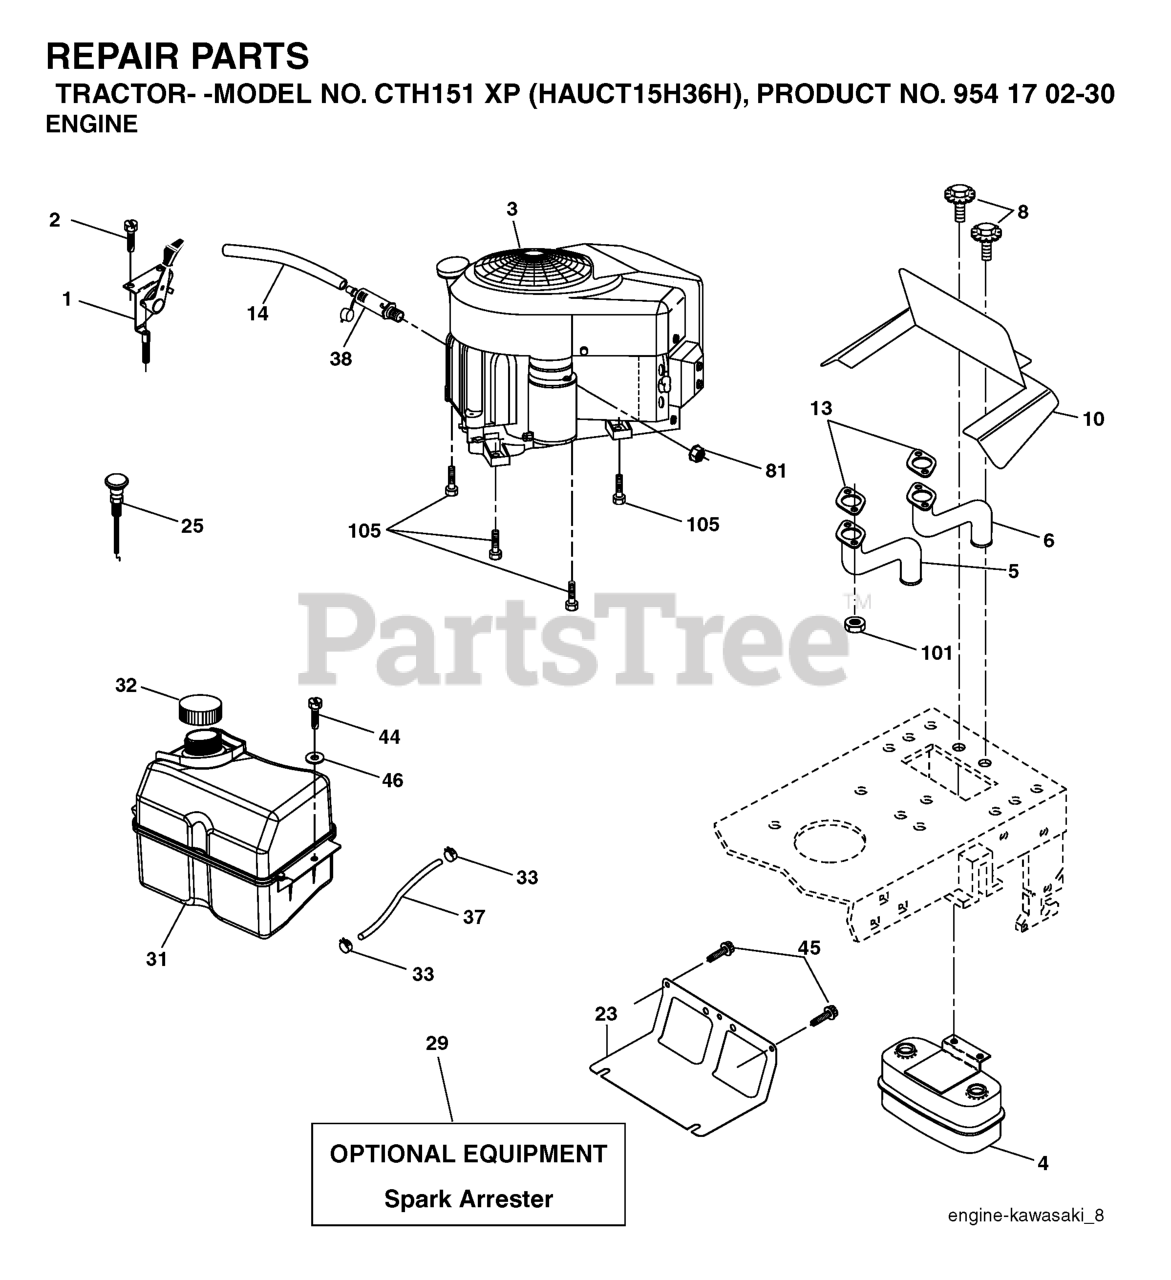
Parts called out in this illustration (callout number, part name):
1	THROTTLE CABLE
2	SCREW
4	MUFFLER.TWIN.CYL.LOW.TONE
5	EXHAUST TUBE LH KAWI
6	EXHAUST TUBE RH KAWI
8	BOLT.5/16-18UNCX3/4 W/SEMS.BLK
10	RP SHIELD HEAT MUFFLER
14	TUBE, DRAIN OIL ASM.
23	SHIELD.BROWNING.DBR.GUARD
25	CONTROL.CHOKE.ERGO.PUSH-IN.BLA
29	KIT.SPARK ARRESTOR 794945 B&S
31	TANK FUEL
32	FUEL CAP
33	HOSE CLAMP
37	LINE.FUEL.20
44	SCREW HEXWSHR 1/4-20X3/4
45	SCREW, 3/8-16X3/4
81	NUT
101	NUT.HEX.FLANGE.TOPLOCK
105	SCREW 3/8-16X1
